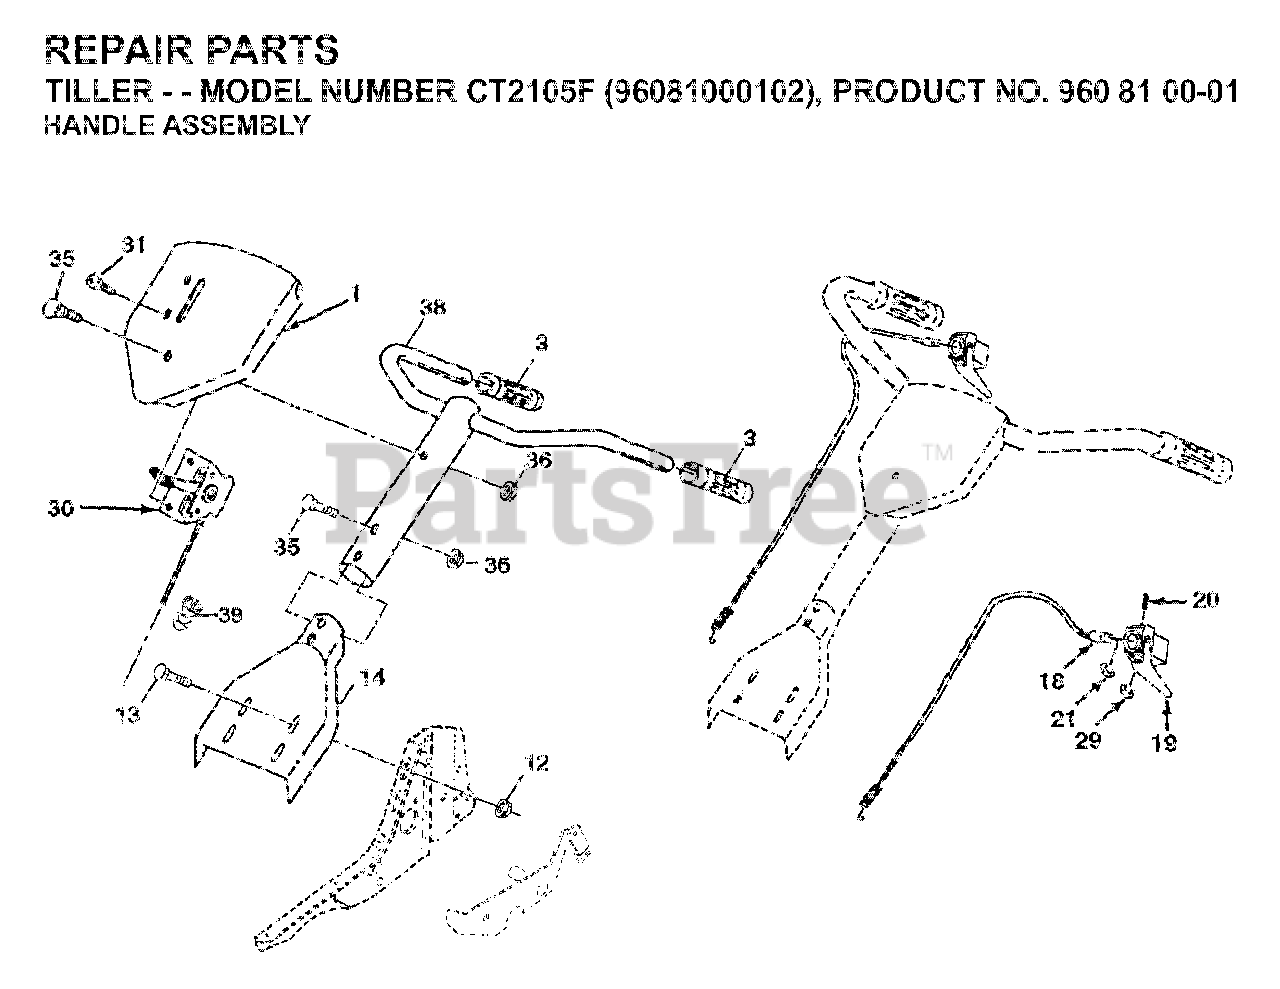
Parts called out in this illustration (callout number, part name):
12	NUT
13	BOLT.RH.SQNK.5/16
14	PANEL ASM. POLE
21	RETAINING RING
29	RETAINING RING
31	SCREW
35	BOLT.5/16-18X2.5
36	LOCKNUT-FLANGE 5/16-18
39	CLIP.ROUTING DUAL
